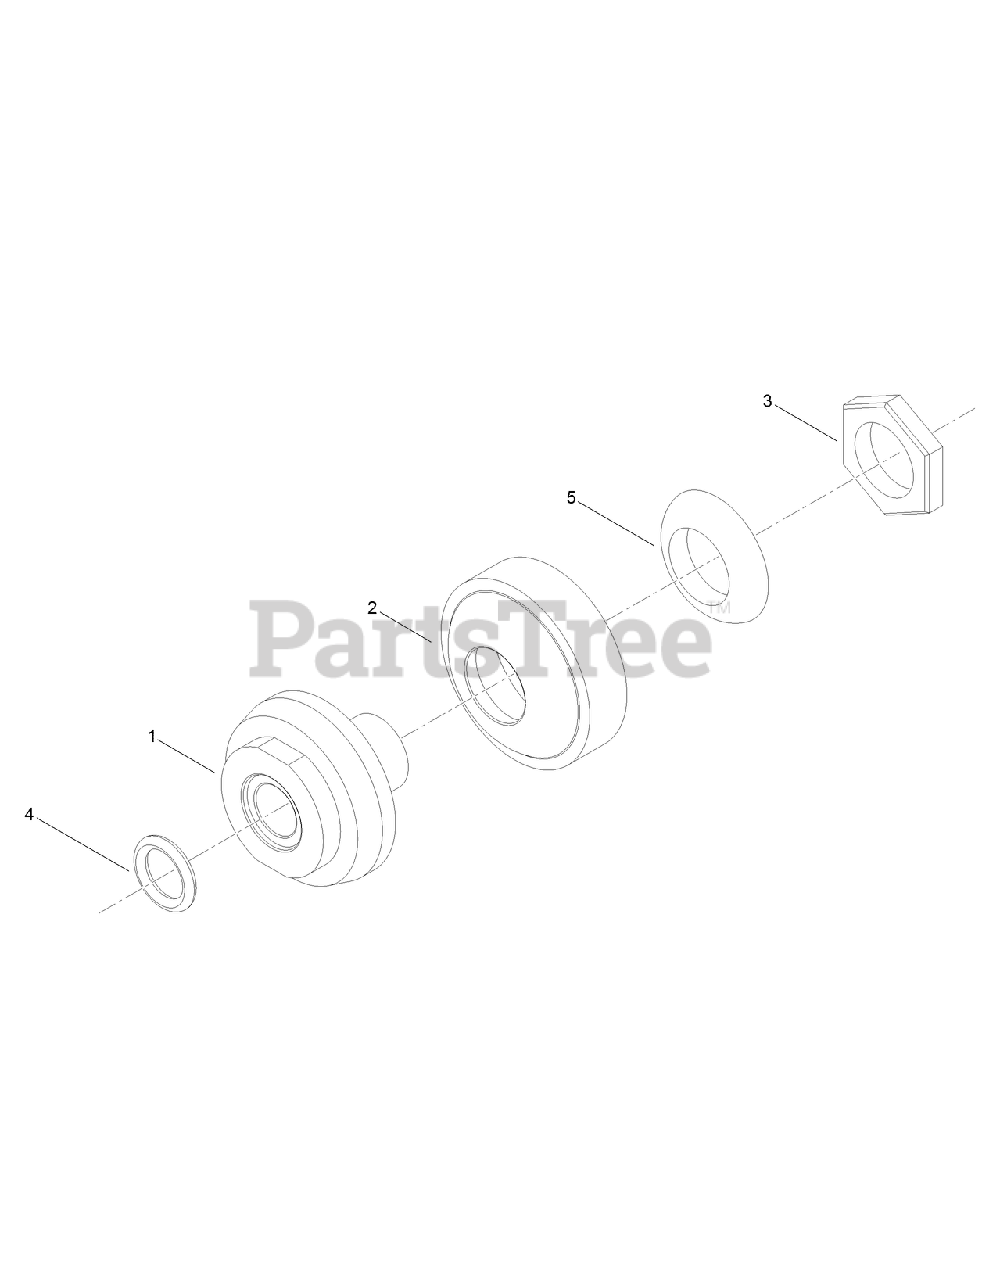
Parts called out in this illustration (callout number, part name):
1	BODY-PISTON
2	CUP-PISTON, GOLD
3	NUT-JAM, HEX
4	O RING-BODY, PISTON
5	RETAINER-CUP, PISTON
